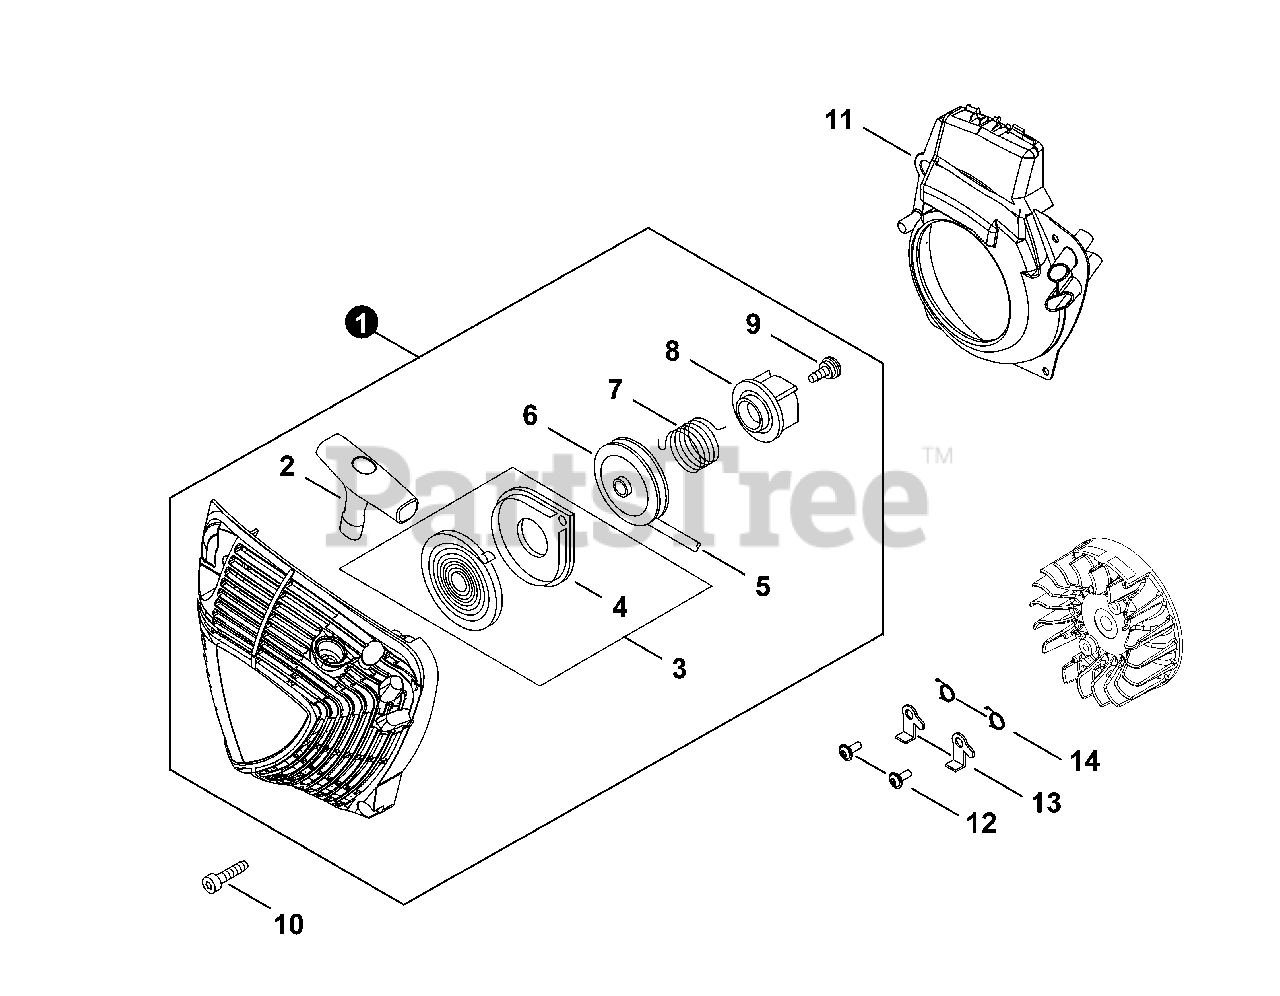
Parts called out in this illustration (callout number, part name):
1	STARTER, RECOIL
2	GRIP, STARTER
3	SPRING KIT, RECOIL
4	SPRING CASE
5	ROPE, STARTER
6	REEL, ROPE
7	SPRING, TORSION
8	PAWL CATCHER
9	SCREW
10	BOLT, TORX 5×20
11	COVER, FAN
14	SPRING, TORSION
